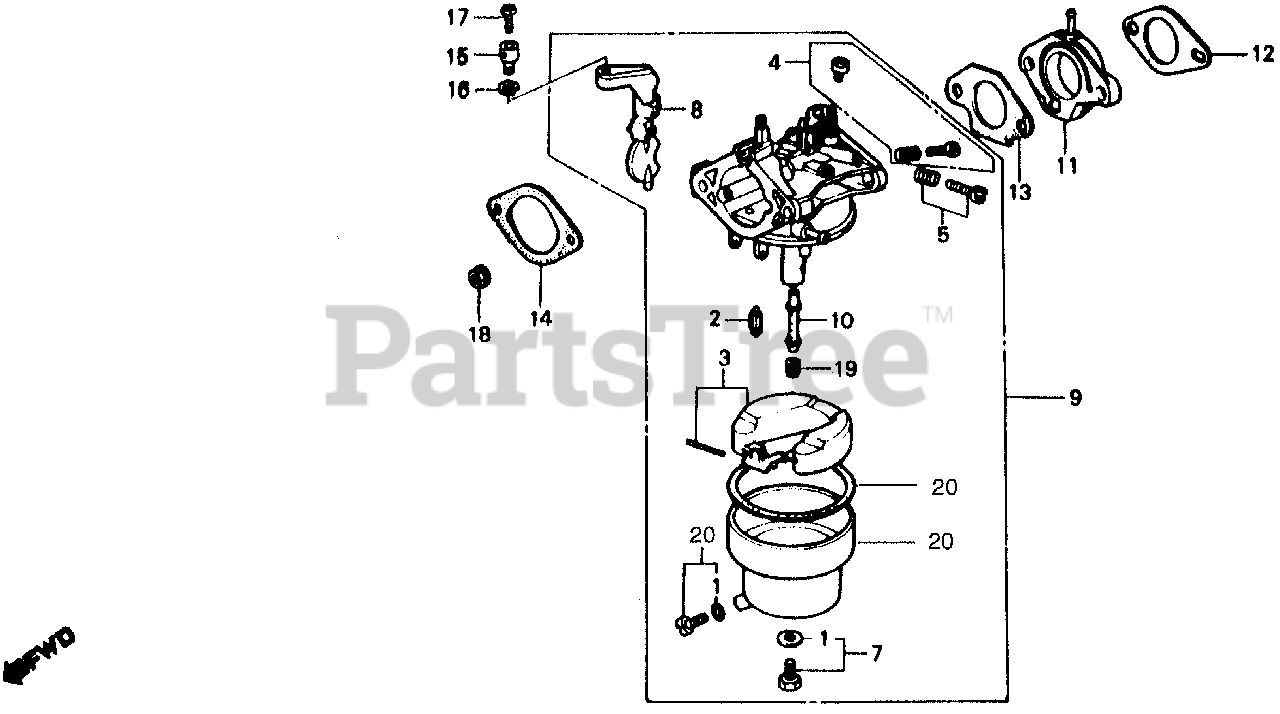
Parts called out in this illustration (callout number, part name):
1	GASKET SET
2	VALVE SET, FLOAT
4	SCREW SET A
5	SCREW SET A
6	SCREW SET, DRAIN
7	SCREW SET B
9	CARBURETOR ASSY. (BB35F E)
9	CARBURETOR ASSY.
10	NOZZLE, MAIN (NOT AVAILABLE)
11	INSULATOR, CARBURETOR (NOT AVAILABLE)
12	GASKET, INSULATOR
13	GASKET, CARBURETOR
14	GASKET, AIR CLEANER
15	HOLDER, CABLE
16	CIRCLIP (5MM)
17	SCREW, PAN (4X8)
18	NUT, FLANGE (6MM)
19	JET, MAIN (#92)
19	JET, MAIN (#95)
19	JET, MAIN (#98)
20	CHAMBER SET, FLOAT
